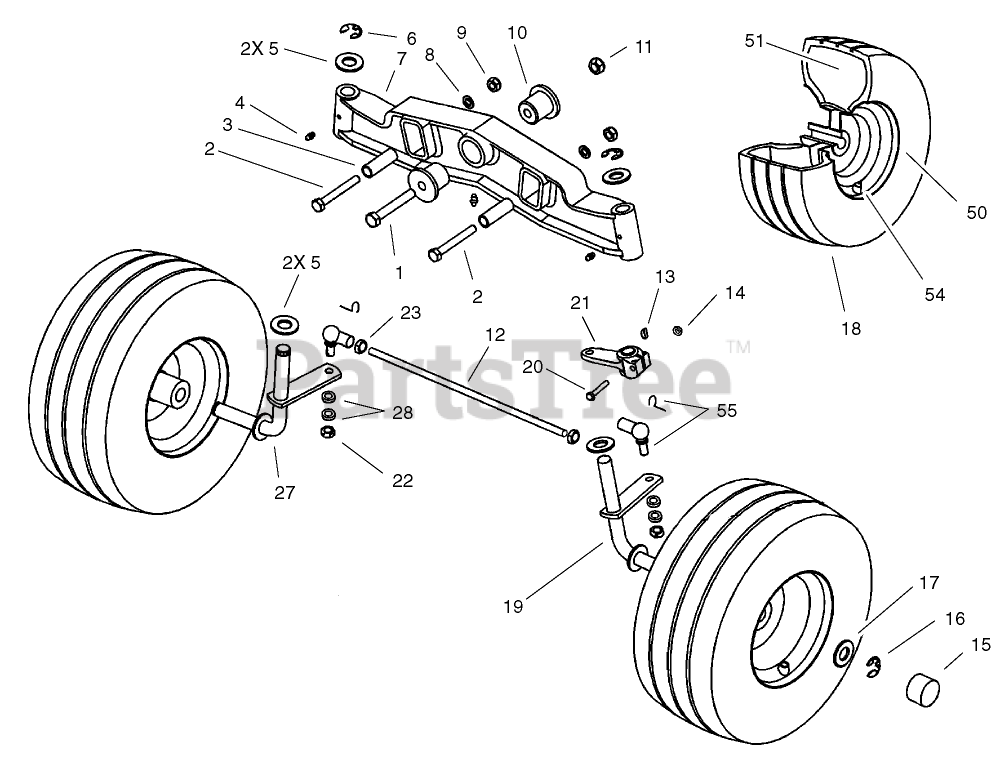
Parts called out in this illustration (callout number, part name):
1	SCREW-HH
2	SCREW-HH
3	SPACER
4	FITTING-GREASE
5	WASHER-FLAT
6	CLIP-SPRING
7	AXLE-FRONT
8	WASHER-FLAT
9	NUT-LOCK, NI
10	BUSHING-AXLE, FRONT
11	NUT-LOCKING, SELF
12	ROD-TIE, FRONT AXLE
13	KEY-WOODRUFF
14	NUT-LOCK
15	CAP-HUB
16	CLIP-SPRING
17	WASHER
19	SPINDLE-LH
20	SCREW-HH
21	LEVER-SPINDLE, STEERING
23	NUT-HEX
27	SPINDLE-RH
28	Washer
55	JOINT-BALL, ANGLE
